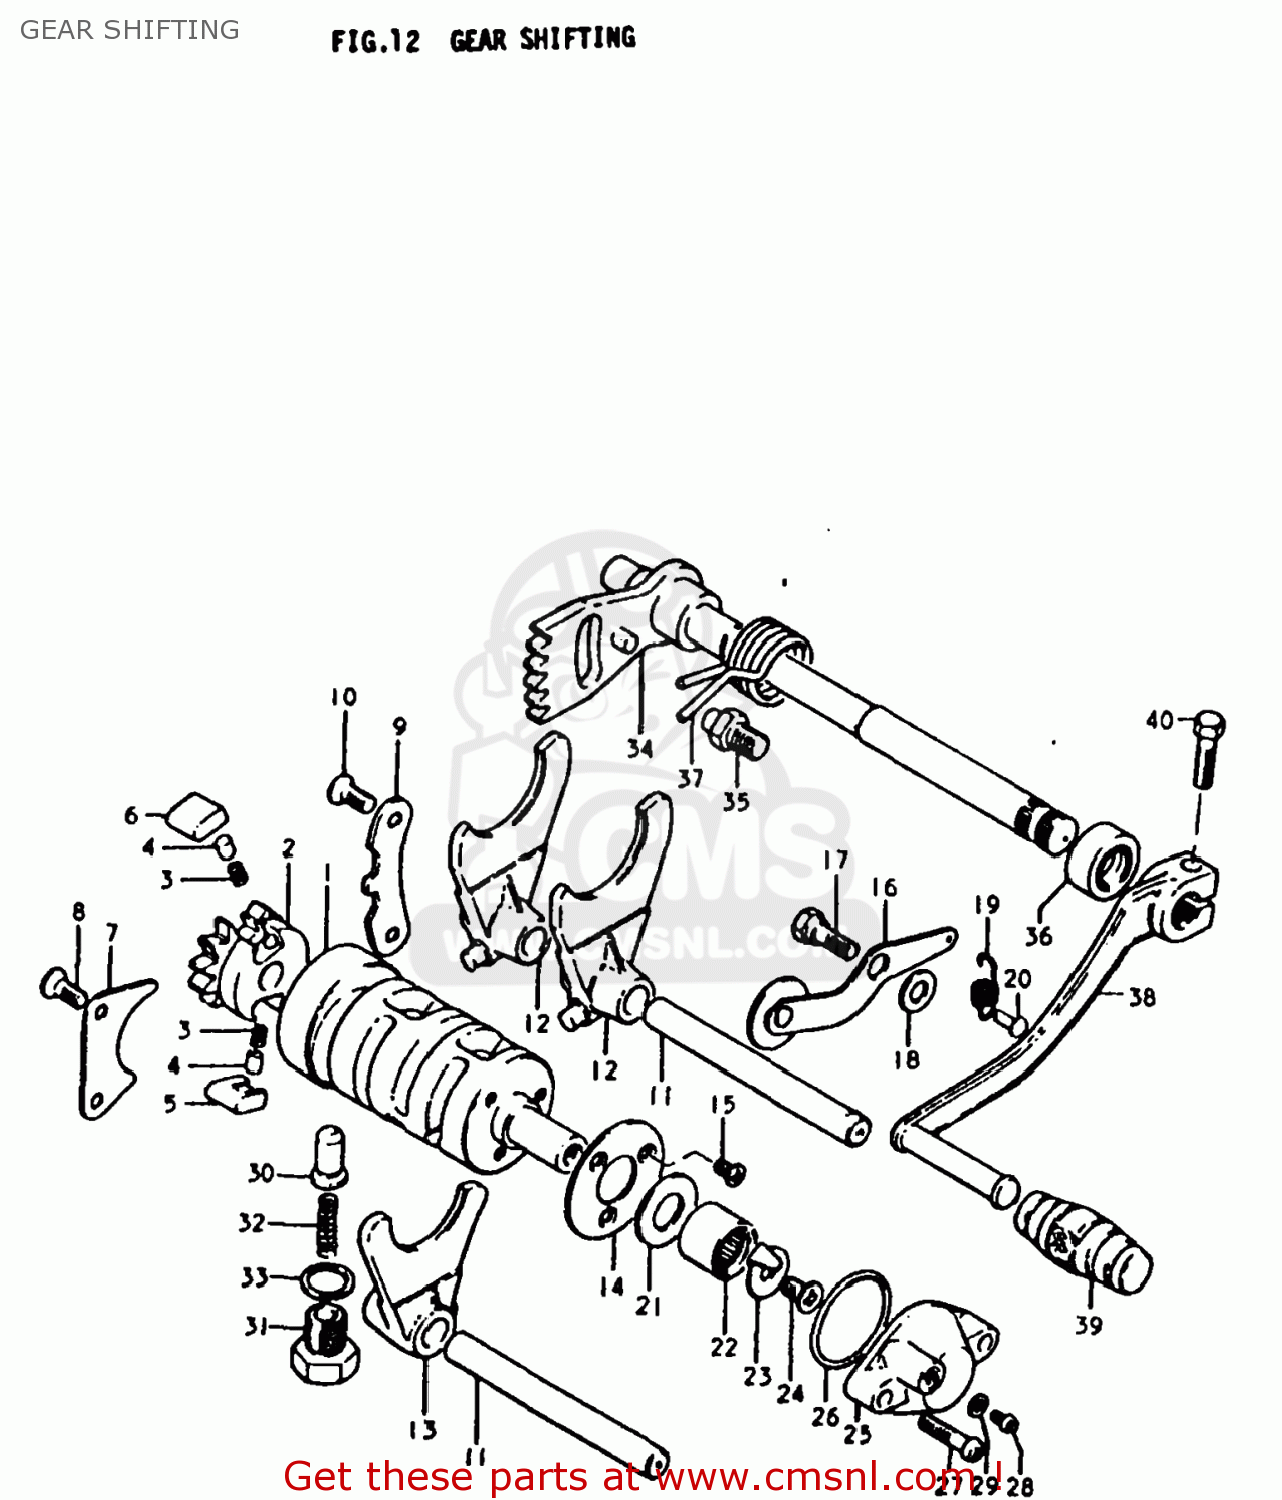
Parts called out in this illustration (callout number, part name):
1	CAM,GEAR SHIFT
2	RETAINER,GEAR SHIFT CAM
3	SPRING
4	PIN(5X8)
5	PAWL,GEAR SHIFT NO.1
6	PAWL,GEAR SHIFT NO.2
7	LIFTER,GEAR SHIFT PAWL
8	SCREW
9	GUIDE,GEAR SHIFTING CABLE
10	SCREW
11	SHAFT,GEAR SHIFT FORK
12	FORK,GEAR SHIFT NO.1
13	FORK,GEAR SHIFT NO.3
14	PLATE,GEAR SHIFT CAM STOPPER
15	SCREW 4X12
16	STOPPER,GEAR SHIFTING
17	BOLT(6X16.1)
18	WASHER
19	SPRING
20	RIVET
21	WASHER
22	ROLLER BEARING (12X18X1
23	CONTACT,GEAR SHIFT SWITCH
24	SCREW
25	BODY,GEAR SHIFT SWITCH
26	O RING(D:1.9,ID:27.7)
27	SCREW 5X20
28	SCREW
29	WASHER
30	STOPPER,GEAR SHIFT CAM NO.2
31	HOLDER,GEAR SHIFT CAM STOP SPR
32	SPRING
33	GASKET(14X19.2X2) (NAS)
34	35
35	STOPPER,GEAR SHIFT CAM
36	OIL SEAL
37	SPRING
38	LEVER ASSY,GEAR SHIFT
39	RUBBER,GEAR SHIFT PEDAL
40	BOLT
